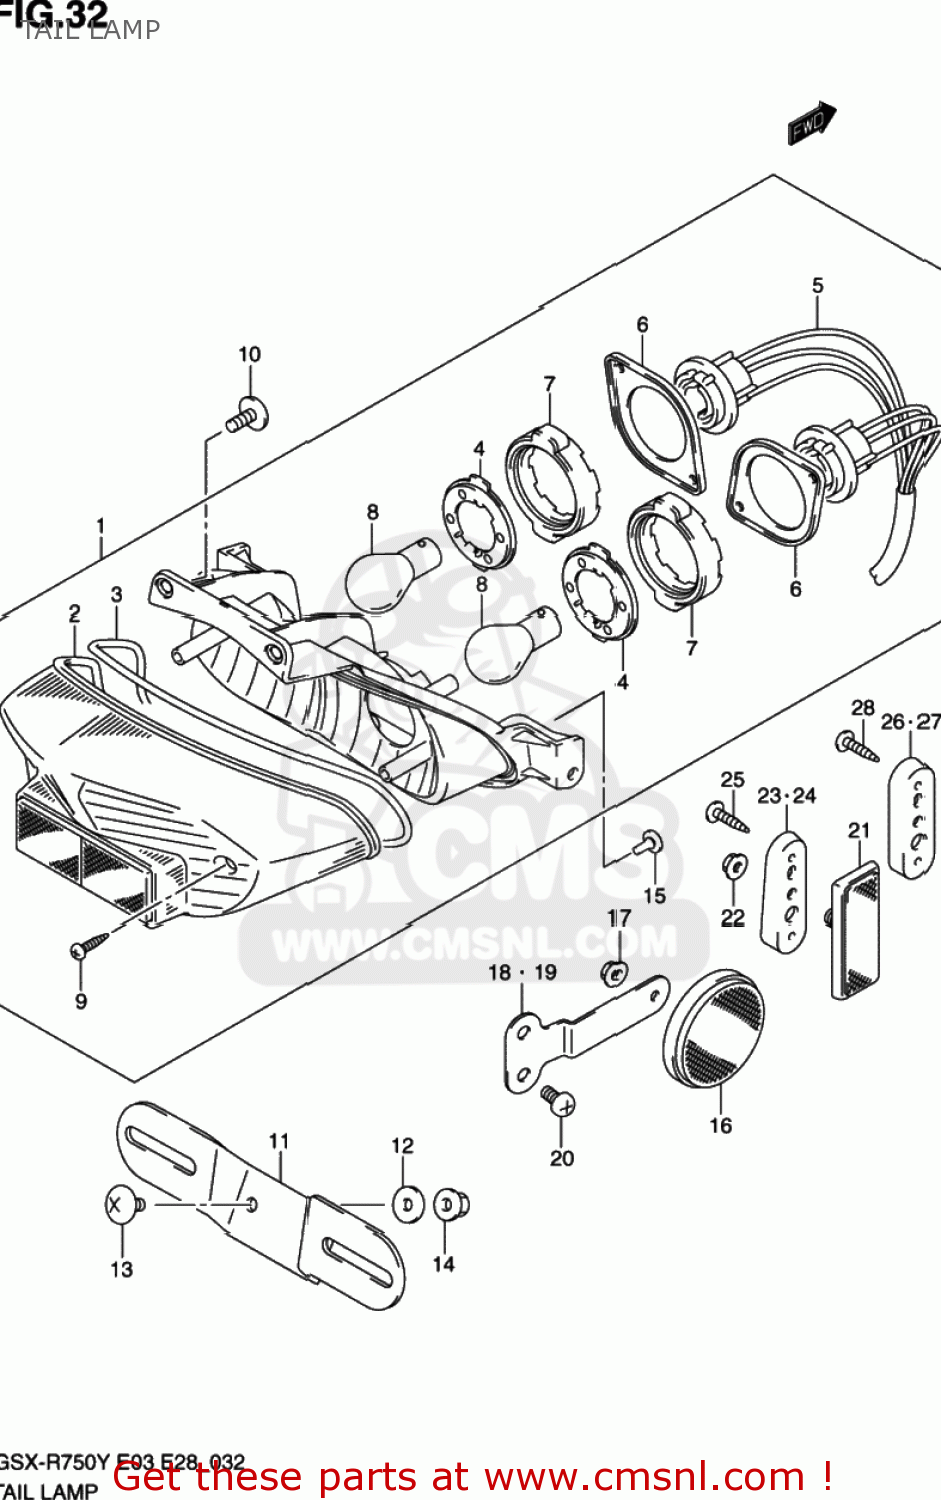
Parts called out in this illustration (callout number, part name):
1	LAMP ASSY,RR COMBINATION
2	LENS
3	GASKET (NAS)
4	PLATE NO.1
5	SOCKET & CORD
6	PLATE NO.2
7	CUSHION
8	BULB(12V21/5W)
9	SCREW
10	SCREW
11	BRACKET,LICENSE PLATE
12	WASHER(6.5X20X1.6)
13	SCREW 6X12
14	NUT
15	CUSHION
16	REFLECTOR ASSY,RR SIDE
17	NUT
18	BRACKET,RR SIDE RR,R
19	BRACKET,RR SIDE RR,L
20	SCREW 6X12
21	REFLECTOR ASSEMBLY,REAR
22	NUT
23	SPACER, RH
24	SPACER,RR SIDE RR,L
25	SCREW
26	SPACER,RR SIDE RR,R
27	SPACER,RR SIDE RR,L
28	SCREW
